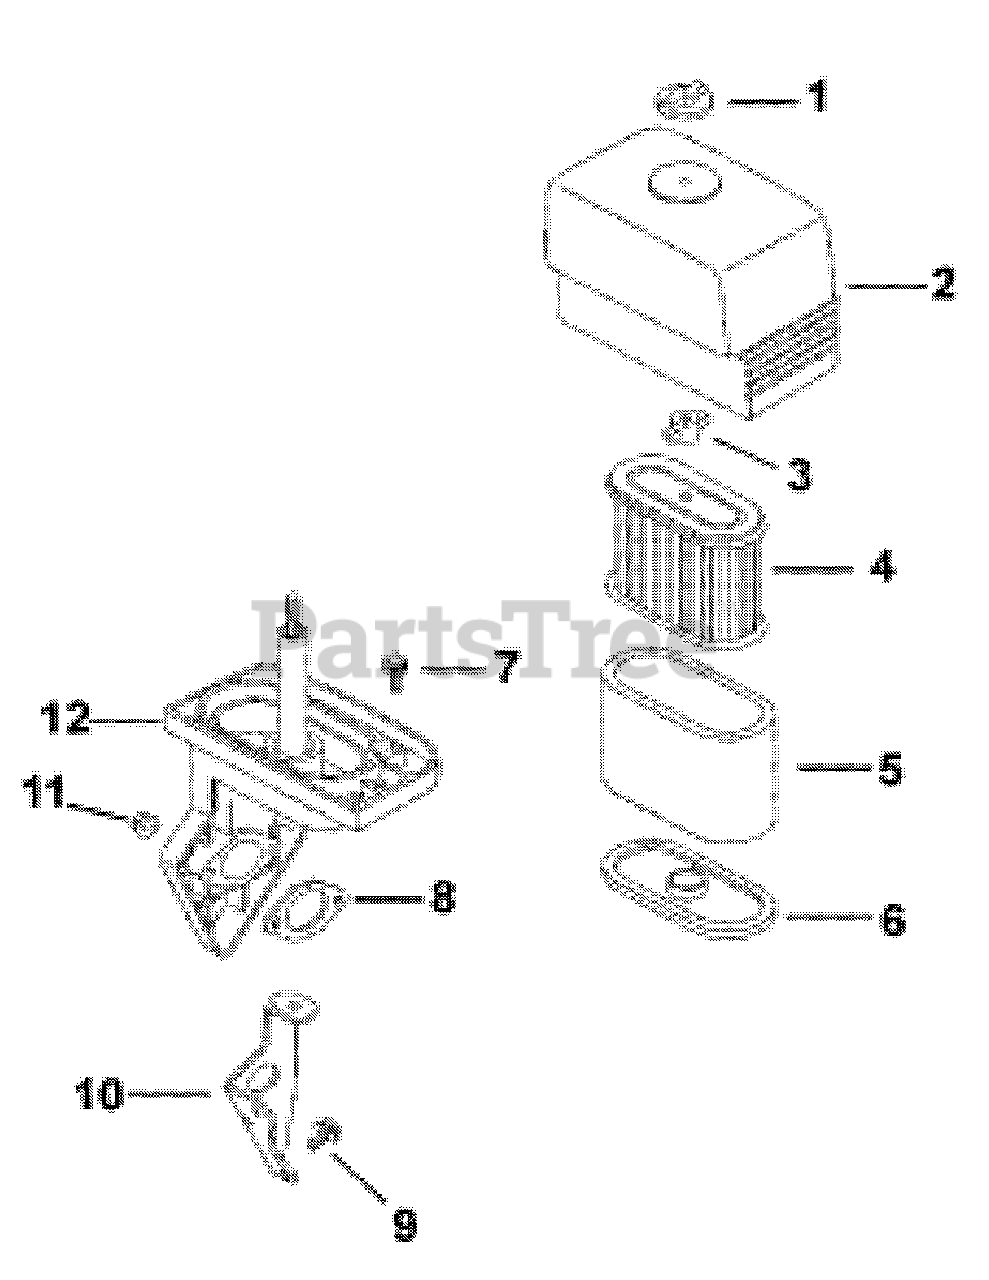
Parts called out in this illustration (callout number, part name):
1	Air Cleaner Cover Knob
2	Air Cleaner Cover
3	Air Cleaner Wing Nut
4	Air Cleaner Element
5	Precleaner Element
6	Air Cleaner Seal
8	Air Cleaner Gasket
9	Hex Flange Screw
10	Air Cleaner Bracket
11	Air Cleaner Nut
12	Air Cleaner Base
